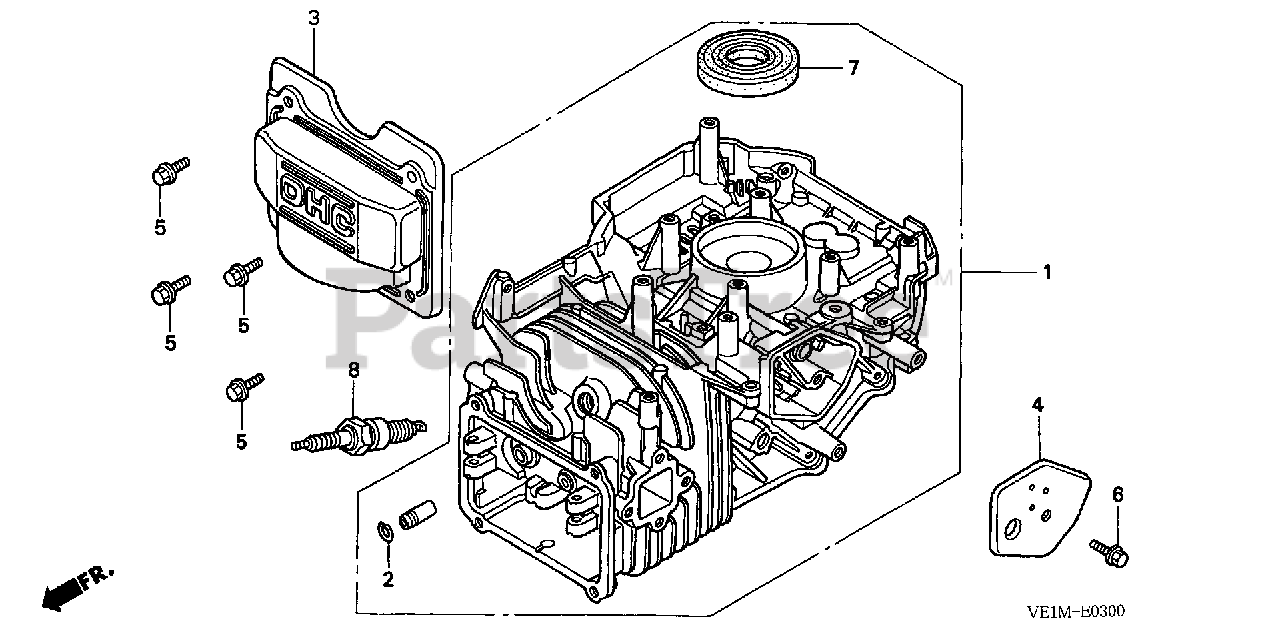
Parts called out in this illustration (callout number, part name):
1	CYLINDER ASSY.
2	CLIP, VALVE GUIDE
3	COVER, HEAD
4	COVER, BREATHER (BREATHER VALVE ASSY.)
5	BOLT, FLANGE (6X12) (CT200)
6	BOLT, FLANGE (6X14) (CT200)
7	OIL SEAL (25.4X62X6)
8	SPARK PLUG (BPR6ES) (NGK)
